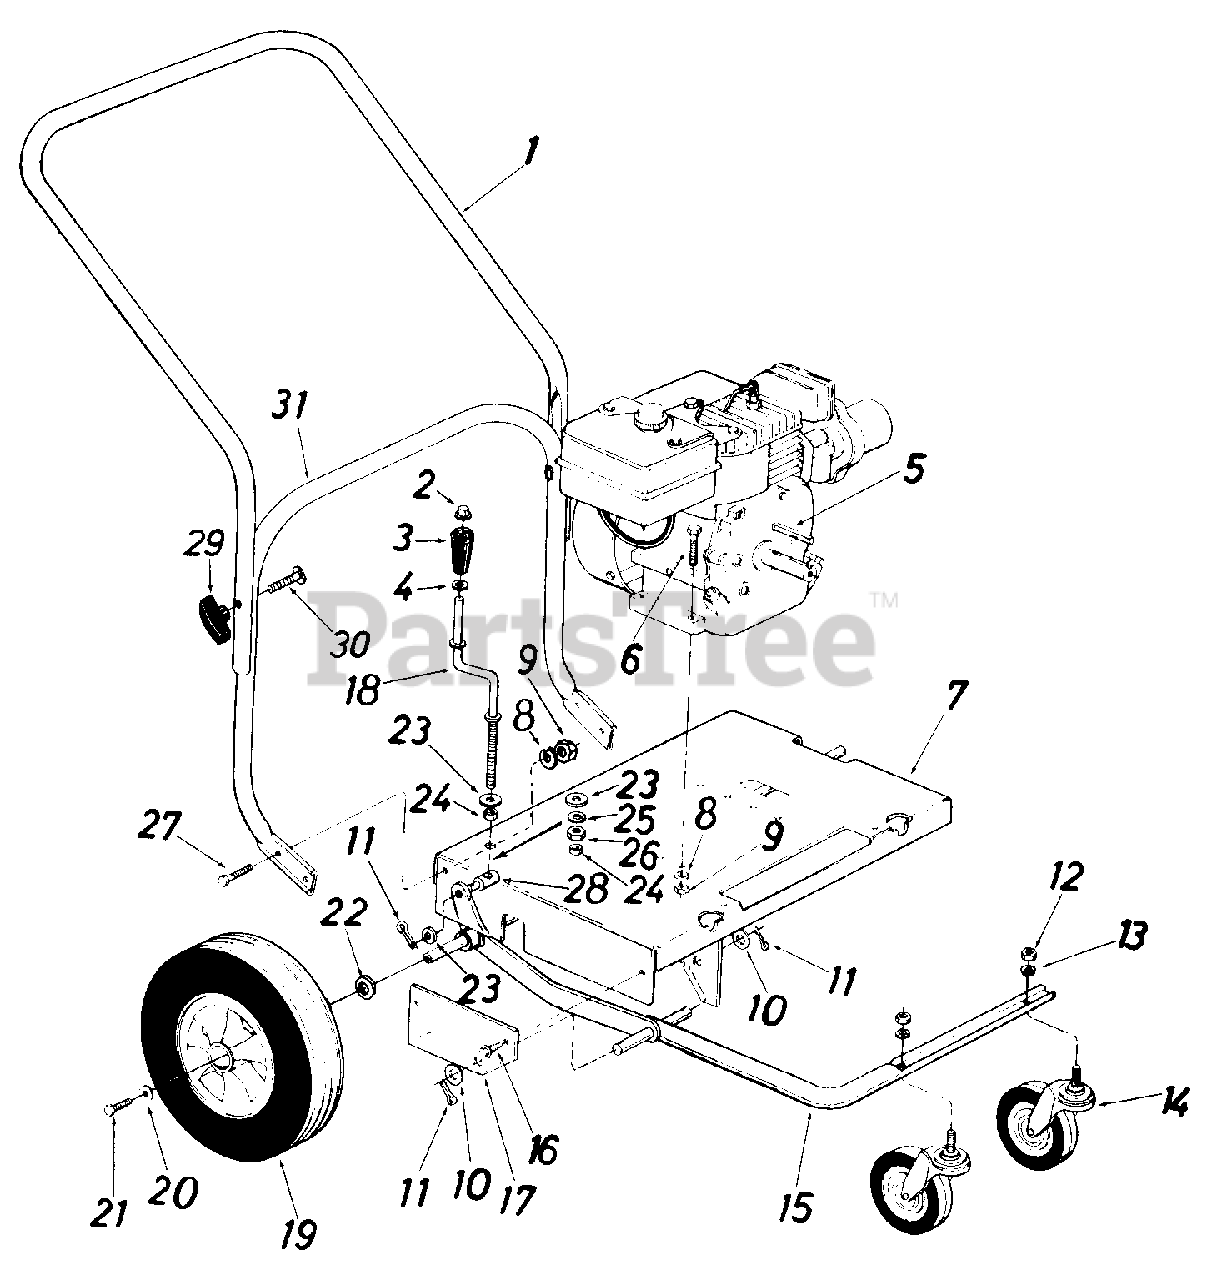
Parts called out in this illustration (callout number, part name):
1	Upper Handle
2	Push Nut 3/8" Rod
3	Crank Knob
4	Fl.Wash. .385" I.D. x .62" O.D.
5	Sq. Key 1/4" x 2.0" Lg.
6	Hex Bolt 5/16-18 x 1.50" Lg.
9	Hex Nut 5/16-18 Thd.
10	Fl.Wash. .63" I.D. x 1.2-O.D.
11	Coter Pin 1/8" Dia. x 1.0" Lg.
12	Hex Nut 1/2-13 Thd.
13	L.Wash. 1/2" I.D.
14	Swivel Caster Wheel 5" Dia. x 1.25"
19	Wheel Ass y. Comp. 12" x 3" (Plastic) (Incl. Bearings)
20	Fl.Wash.34" I.D. x .87" O.D.
21	Hex Locking Bolt 5/16-24 x.62" Lg.
22	Fl.Wash.
23	Fl.Wash. .38" 1.D. x .57" O.D.
24	Spacer .382 " I .D. x .50" O.D. x .180" Lg.
25	L.Wash. 3/8" I.D.*
26	Hex Nut 3/8-8 Thd.
27	Hex Bolt 5/16-18 x .75" Lg.
28	Ferrule
29	Hand Knob
30	Carriage Bolt 5/16-18 x 2.0" Lg.
31	Lower Handle
